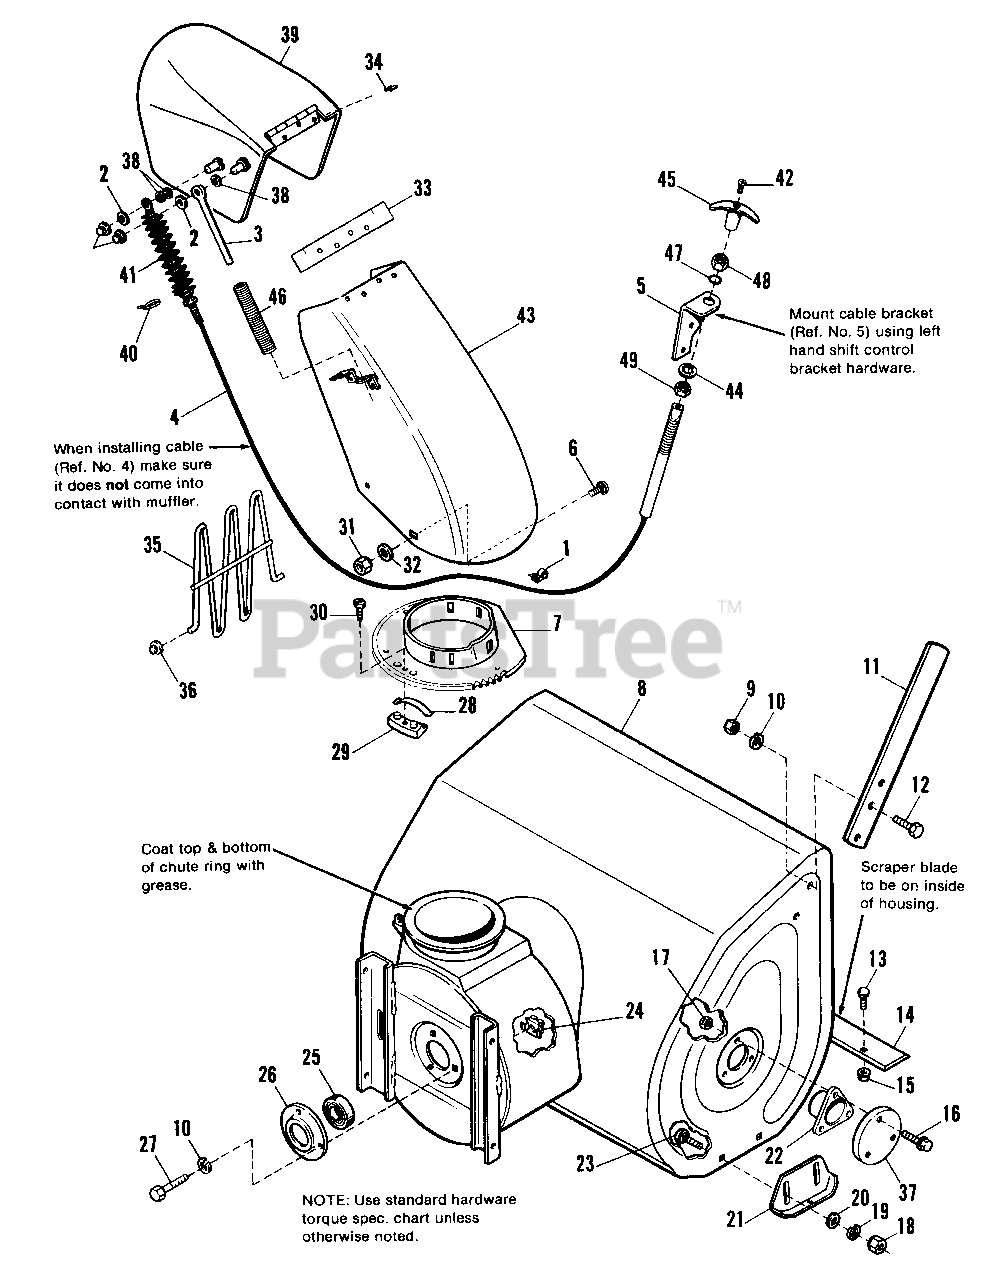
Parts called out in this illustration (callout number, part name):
2	WASHER, Flat
3	ROD, Spring
4	CABLE ASSY. (Incl. Ref. Nos. 40-42, 44, 45 & 47-49)
5	BRACKET, Cable
6	BOLT, Carriage, 1/4-20 x 5/8
7	GEAR, Chute
8	HOUSING ASSY., Auger, 24" (Used on Mfg. No. 1691368)
8	HOUSING ASSY., Auger, 28" (Used on Mfg. No. 1691370)
8	HOUSING ASSY., Auger, 32" (Used on Mfg. No. 1691371 & 1691716)
9	NUT, 5/16-18 (1691370, 1691371 & 1691716 only)
10	LOCKWASHER, 5/16 (Qty. 7 on 1691370, 1691371 & 1691716)
11	CUTTER, Drift (1691370, 1691371 & 1691716 only)
12	CAPSCREW, Hex Hd., 5/16-18 x 3/4 (1691370, 1691371 & 1691716 only)
13	BOLT, Carriage, 5/16-18 x 5/8 (Qty. 7 on 32" models)
14	BLADE, Scraper, 24" (Used on 1691368)
14	BLADE, Scraper, 28" (Used on 1691370)
14	BLADE, Scraper, 32" (Used on 1691321, 1691716)
15	LOCKNUT, Flange, 5/16-18 (Qty. 7 on 1691371 & 1691716 only)
16	CAPSCREW, Hex Flange Whizlock, 5/16-18 x 7/8
17	NUT, Hex, Center Lock, 5/16-18
18	NUT, Hex, 3/8-16
19	LOCKWASHER, 3/8
20	WASHER, Flat, 5/16
22	BEARING, Auger
23	BOLT, Carriage, 3/8-16 x 3/4
24	NUT, Retainer, 5/16-18
25	BEARING, Ball
26	RETAINER, Bearing
27	CAPSCREW, Hex Hd., 5/16-18 x 17/64
29	HOLD DOWN, Chute
30	SCREW, Plastite #10
31	LOCKNUT, Nylon, 1/4-20
32	WASHER, Flat, 1/4
33	LlNER, Chute
34	RIVET, Pop
35	GUARD, Chute
36	PUSH NUT
37	BEARING, Cap
39	DEFLECTOR ASSY.
40	TIE, Self-Locking, Cable Assy.
41	BOOT, Water
42	SCREW, Pan Hd., #8-32 x 11/16
43	CHUTE ASSY.
44	LOCKWASHER, Int. Tooth
45	HANDLE, Cable
47	"O" RING, Cable Assy.
48	FITTING, Cable Assy.
49	NUT, 5/16-18, Cable Assy.
